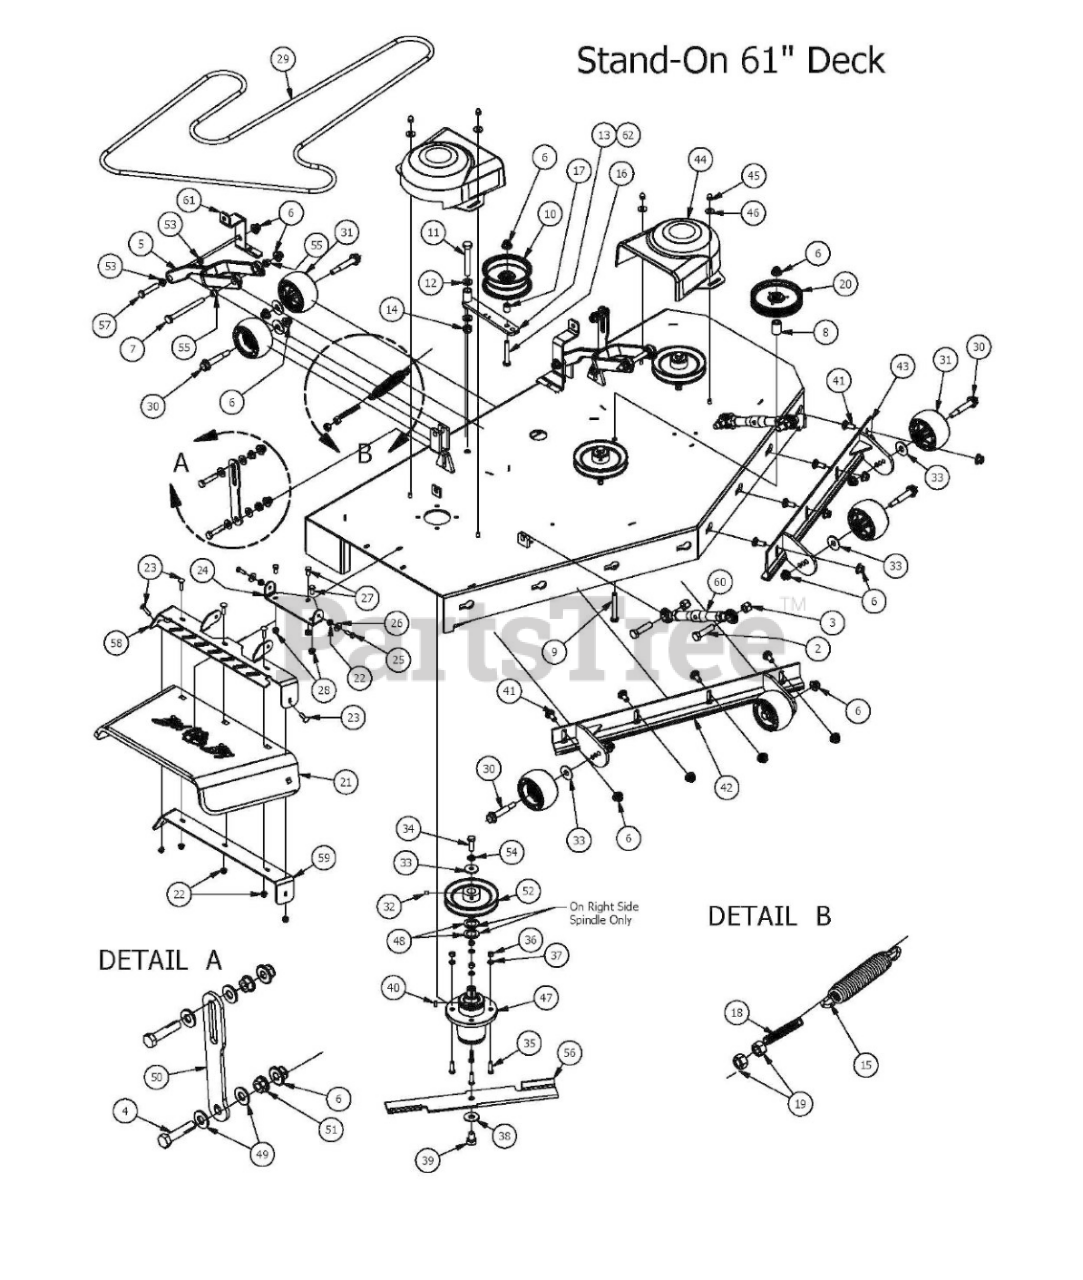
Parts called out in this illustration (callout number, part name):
1	61" 2015 Stand-On Deck (Welded Assembly)
2	5/8" x 2 1/2" Hex Bolt
3	5/8 Std NC Nylock Nut
4	1/2-13X 2-1/4 GR Hex Bolts
5	Deck Arm Assembly
6	1/2-13 Nylon Flange Nut
7	1/2" x 5 1/2" Bolt
8	Idler Pulley Standoff
9	1/2 x 3 1/2 Flange Bolt Grade 8
10	5 3/4" Deck Idler Pulley
11	5/8" x 4" Hex Bolt
12	.630 ID Plastic Washer
13	Deck Idler Arm
14	5/8" Nylock (1/2 Jam)
15	2009 Deck/Pump Idler Spring
16	1/2-13 x GR 5 Hex Bolt Zinc
17	Spacer 3/4 OD x 1/2 ID x 314 Length
18	All Thread-Pump Idler Tensioner
19	1/2" Hex Nut
20	5-3/4 Idler Pulley-Capitol Stampings
21	5/16" Nylock Flange Nut Zinc
22	5/16" x 1 1/4" Carriage Bolt
23	Discharge Chute Hanger (deck mounted)
24	Rubber Discharge Chute
25	5/16" x 1" Bolt
26	.360 ID Plastic Washer
27	3/8" x 3/4" Hex Bolt
28	3/8" Flange Nut
29	54" MZ Magnum Belt - B138
30	Deck Wheel Bolt
31	Anti-Scalp Rollers
32	5/16 Set Screw
33	1/2" Belleville Washer
34	1/2"-20 x 1 1/2 - Grade 5 Fine Thread Bolt
35	3/8" x 1 1/4" Hex Bolt
36	3/8-16 Hex Nuts Zinc
37	3/8" Lock Washer
38	5/8" Flat Washer
39	5/8" x 1 1/2" Grade 8 Hex Bolt (Fine)
40	1/4" x 1" Key
41	1/2" x 1 1/4 Carriage Bolt
42	61 Deck Adustable Front (Right)
43	61 Deck Adustable Front (Left)
44	Pulley Cover
45	Acorn nut-pulley Cover
46	.360 ID Plastic Washer-Black
47	OUTLAW SPINDLE ASSEMBLY
48	1 1/8" Flat Spacer
49	.505 Nylon Spacer
50	Longer deck hanger
51	1/2" Flange Nut
52	6 1/4" Drive Pulley
53	Flange Bushing For Lower Deck Arm
54	1/2" Lock Washer
55	Flange Bushing For Upper Deck Arm
56	61 inch Fusion Blade
57	1/2" x 3" Hex Bolt
58	60" Discharge Chute Upper Hanger
59	60" Discharge Lower Bracket
60	Turnbuckle
61	Stand-On Deck Stop
62	Deck Idler Arm Assembly (Includes 6,10,13,16,17)
